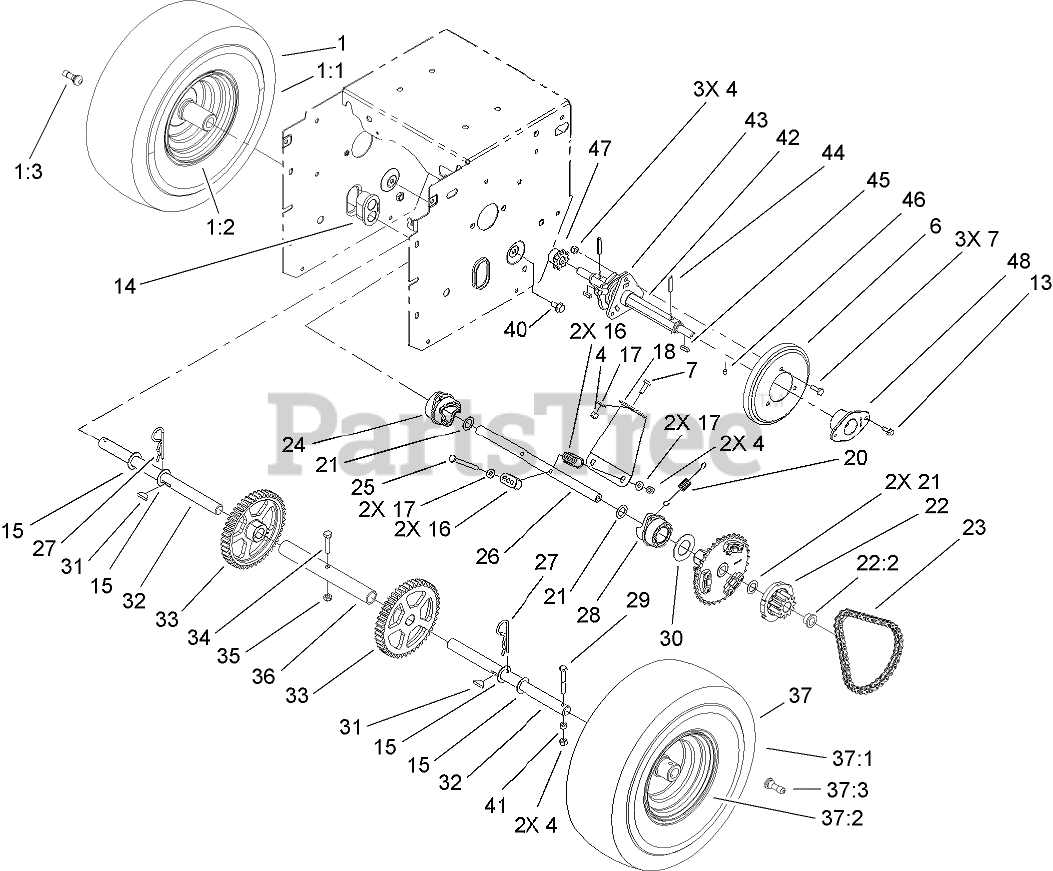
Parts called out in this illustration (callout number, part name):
1	RH WHEEL AND TIRE ASM
1:2	RIM-TIRE
1:3	STEM-VALVE
4	NUT-LOCK, NI
6	WHEEL-FRICTION
7	SCREW-HH
13	SCREW-HWH
14	BEARING-AXLE
15	WASHER-THRUST
16	GUIDE-COLLAR
17	WASHER-FLAT
18	BRACE-COLLAR, SHIFT
20	SPRING-EXTENSION
21	WASHER-FLAT
22	11T GEAR ASM
22:2	BUSHING-FLANGE
23	CHAIN-ROLLER
23	LINK-CONNECTING
24	COLLAR-SHIFT, RH
25	SCREW-HH
26	SHAFT-INTERMEDIATE
27	PIN-HAIR
28	COLLAR-SHIFT, LH
29	SCREW-HH
30	WASHER-THRUST
31	KEY-WOODRUFF
32	SHAFT-AXLE
33	GEAR-AXLE, 44 TOOTH
34	SCREW-HH
35	NUT-LOCK, NI
36	TUBE-AXLE
37	LH WHEEL AND TIRE ASM
37:2	RIM-TIRE
37:3	STEM-VALVE
40	SCREW-HWHTF
41	SPACER-BLADE, ROTOR
42	SHAFT-HEX
43	TRUNNION-HEX
44	PIN-ROLL, SLOTTED
45	KEY-SQUARE
46	SCREW-HSH
47	SPROCKET-8 TOOTH
48	RETAINER-BEARING
